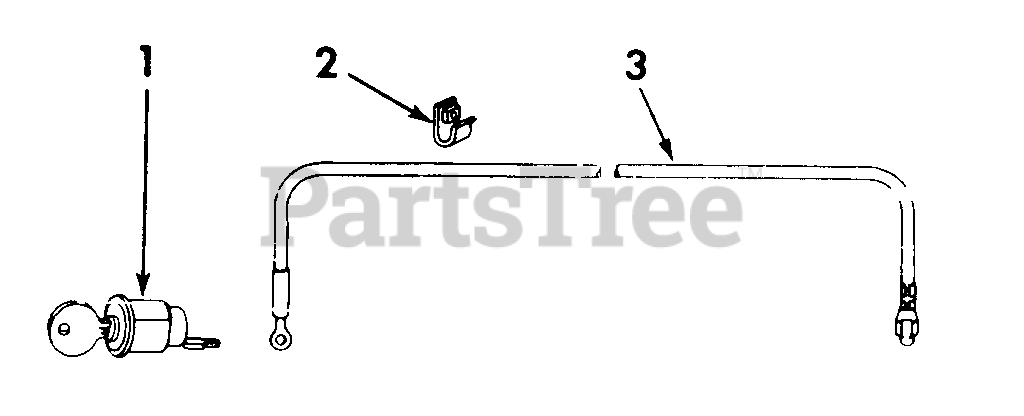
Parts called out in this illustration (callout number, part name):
1	SWITCH ASSY MAGNETO IGNITION
2	CLIP MAGNETO GROUNDING SWITCH CABLE REAR
3	CABLE ASSY, SWITCH
